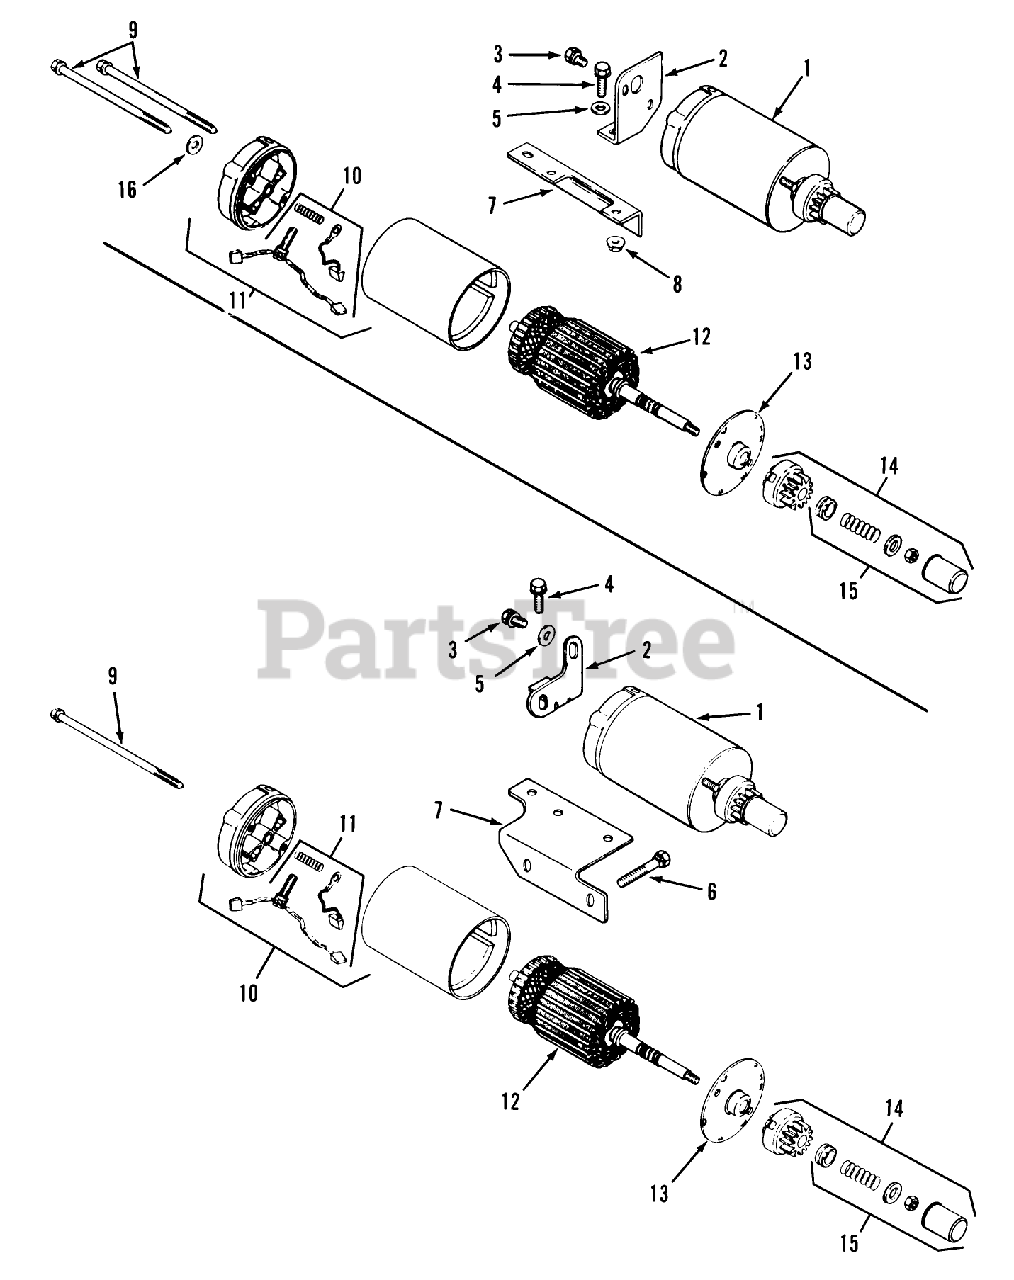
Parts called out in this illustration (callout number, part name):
1	KOHLER 41-098-04
2	KOHLER 41-120-06
3	KOHLER X-67-62
4	KOHLER X-5-1
5	KOHLER X-25-53
6	KOHLER X-159-2
7	KOHLER 41-126-25
8	KOHLER X-799-1
9	KOHLER 41-086-19
10	KOHLER 41-227-04
11	VNDR #52-755-15
12	KOHLER 47-170-02
13	KOHLER 41-227-03
14	KOHLER 47-755-07
15	KOHLER 47-755-13
16	KOHLER X-25-53
